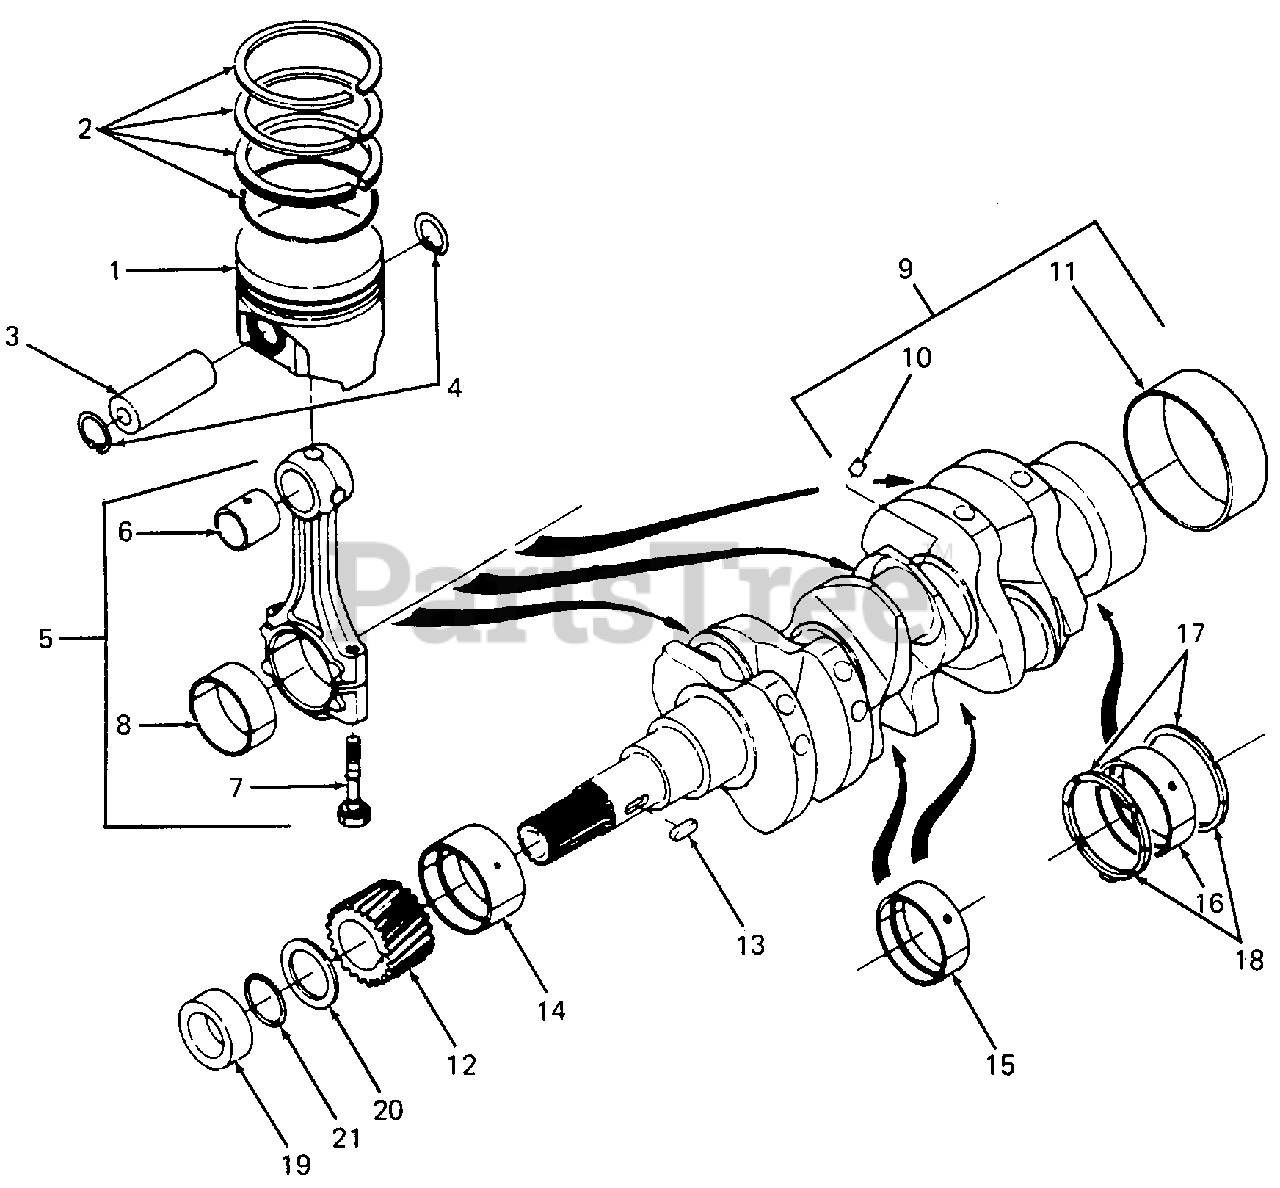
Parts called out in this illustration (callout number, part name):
2	Ring, Piston (Std)
4	Ring, Retaining
5	Rod Assy, Connecting
6	Bushing, Piston Pin
7	Bolt, Connecting Rod
8	Bearing, Connecting Rod (Std)
9	Crankshaft Assy
11	Sleeve, Crankshaft
12	Gear, Crankshaft
14	Bearing, Crankshaft Main (Std)
15	Bearing, Crankshaft Main (Std)
16	Bearing, Crankshaft Main (Std)
17	Bearing, Side (Std)
18	Bearing, Side (Std)
19	Collar, Crankshaft
20	Slinger, Crankshaft Oil
